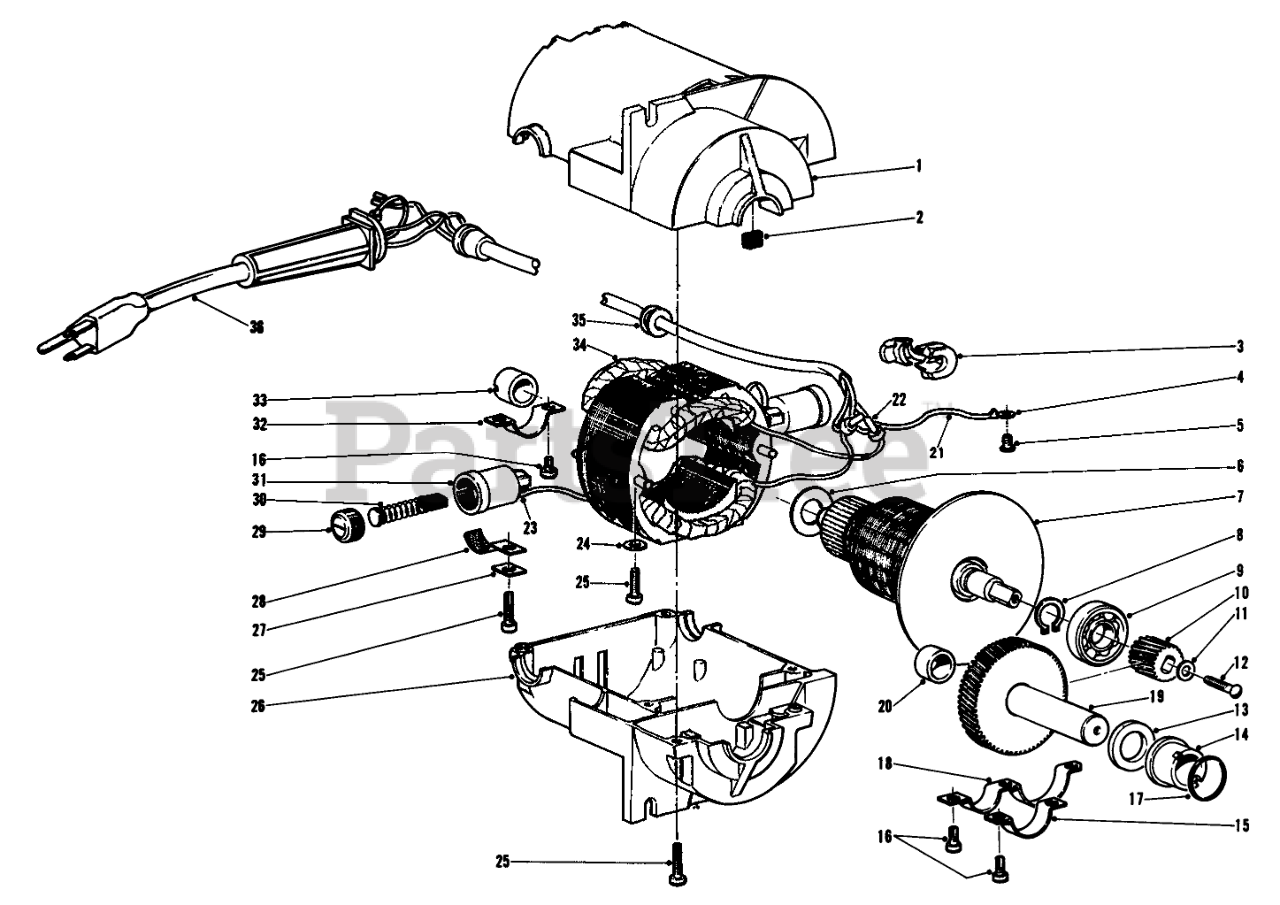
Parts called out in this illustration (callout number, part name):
1	Motor Case
2	Felt-Oil
3	Strain Relief
4	Terminal
5	Screw, Ground
6	Washer-Fiber
7	Armature Assembly
8	Ring-Snap
9	Bearing, Armature-Front
10	Pinion, Armature
11	Bracket-Seat Pivot
12	Collar
13	Ass-y Frame
14	Bushing, Spindle-Front
15	Ass-y. Hoodstand
16	Screw, Bushing Clamps
17	O-RING
18	Ass-y. Control
19	Spindle & Gear Assembly
20	Bushing, Spindle-Internal
21	Ground Wire
22	Connector
23	Clip Terminal, Brush Holder
24	Coupling
25	Screw
26	Motor Cover
27	Axle, R.H.
28	Clamp, Brush Holder
29	Cap, Brush
30	Brush & Spring Assy.
31	Brush Holder
32	Clamp, Armature Bearing Rear
33	Bushing, Armature-Rear
34	Stator Assy.
35	Grommet
36	Cord Assembly Canadian
